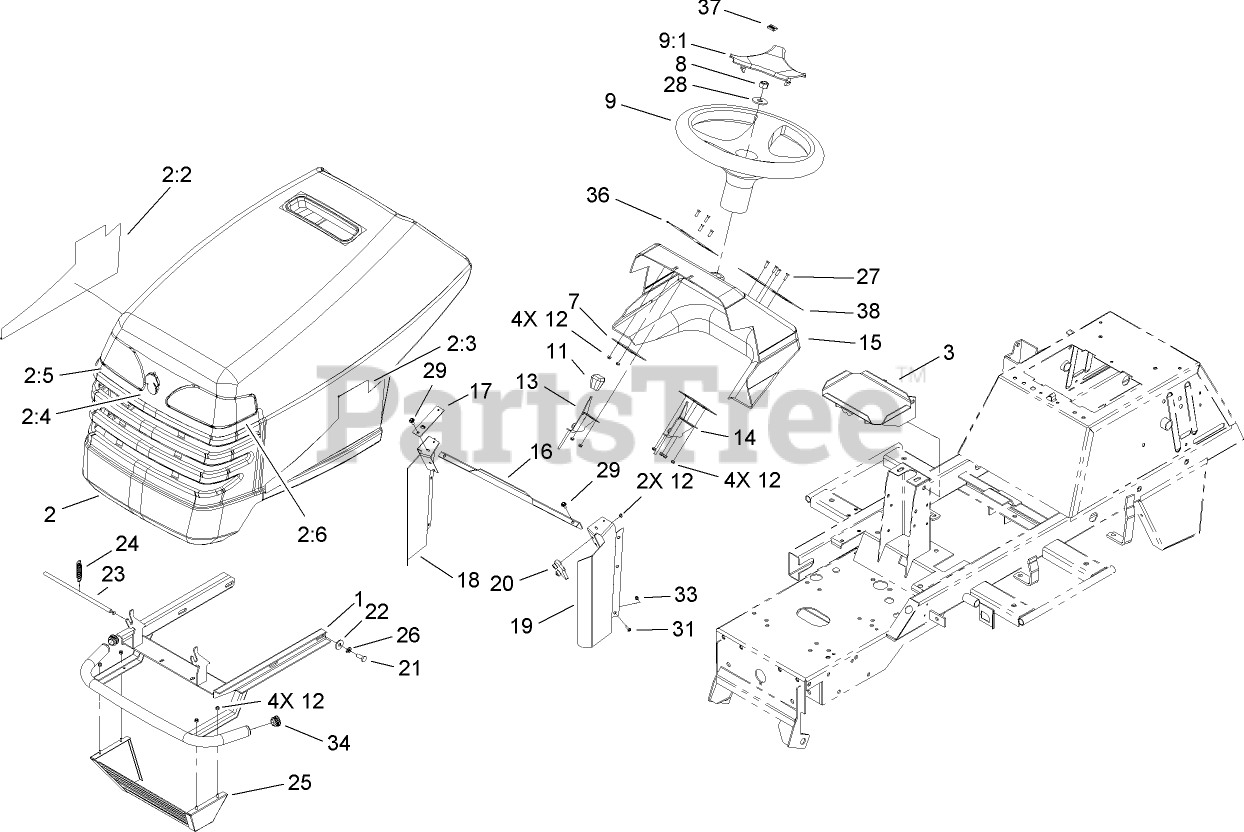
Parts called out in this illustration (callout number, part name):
1	SUPPORT-BUMPER
2	HOOD ASM
2:2	DECAL-HOOD, RH
2:3	DECAL-HOOD, LH
2:4	EMBLEM
2:5	LENS-HEADLAMP, RH
2:6	LENS-HEADLAMP, LH
3	TRAY-BATTERY
8	NUT-HEX
9	WHEEL-STEERING
9:1	COVER-WHEEL, STEERING
12	NUT-LOCK
13	CONTROL-THROTTLE (TWIN)
14	CONTROL-CHOKE (TWIN)
15	PANEL-DASH
17	BRACKET
18	PANEL-RIGHT
19	PANEL-LEFT
20	LATCH-HOOD
21	SCREW-HH
22	WASHER-PLAIN
23	BAR-SAFETY
24	SPRING-HOOD
25	GUARD-MUFFLER
28	Washer
33	NUT-HEX
34	PLUG-END, TUBE
37	DECAL
38	DECAL-CHOKE/PTO
